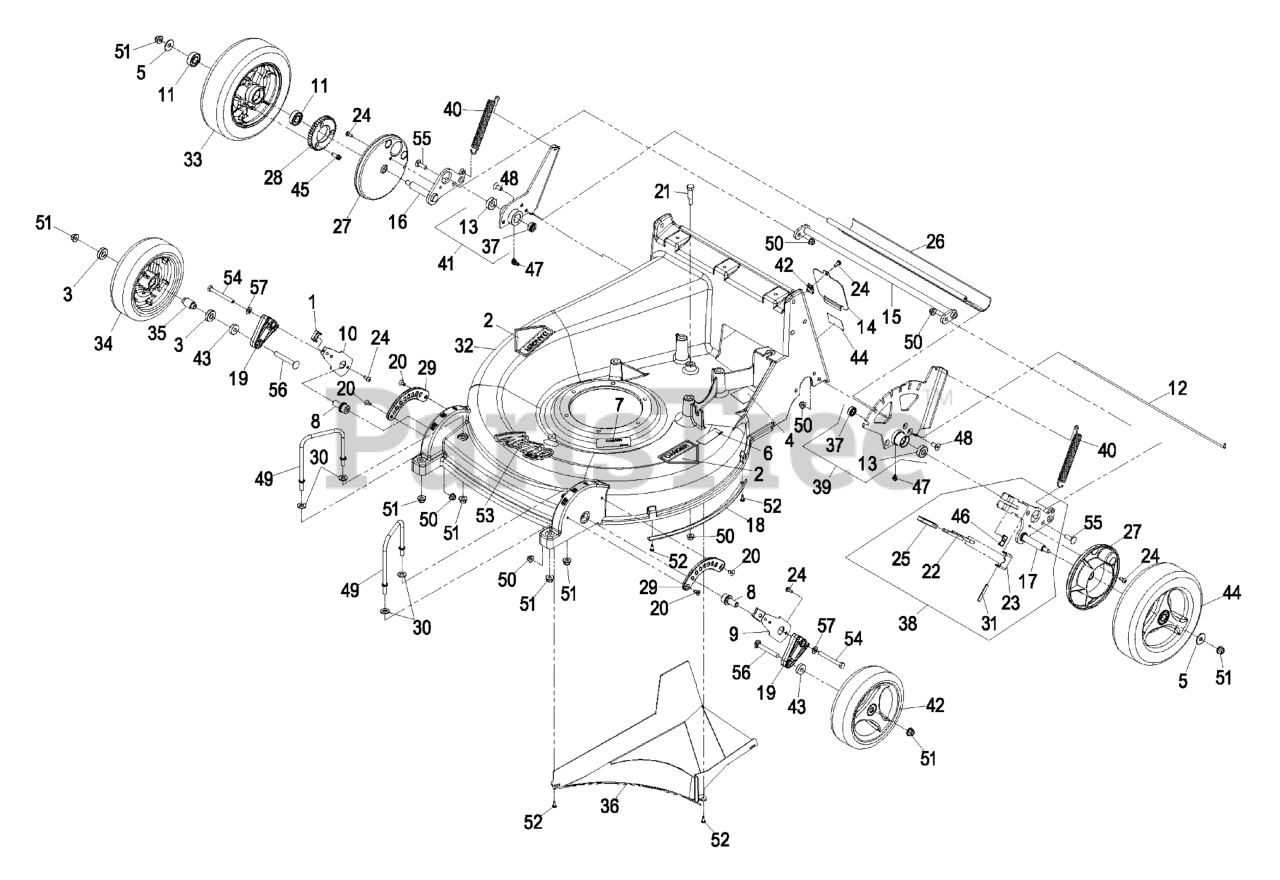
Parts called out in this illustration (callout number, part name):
1	KNOB-ARM
2	DECAL-DANGER
3	BEARING-WHEEL
4	Decal, Grease
6	DECAL-BLADE
7	DECAL-COVER, MISSING
8	BUSHING-PIVOT, WHEEL
9	LH FRONT SPRING ARM ASM
11	BEARING-BALL
13	BEARING-AXLE, REAR
16	Wld, Axle Arm Rh
18	GUARD-EDGE
21	SCREW-SHOULDER, HH
22	Lever, Lift
23	BRACKET-PIVOT, LIFT
24	SCREW-TP
25	COVER-HANDLE
27	COVER-GEAR
28	GEAR-DRIVEN
29	QUADRANT-FRONT
30	WASHER-FLAT
31	PIN-ROLL
32	ASM,26 DECK W/DECALS
33	ASM,10" TIRE AND WHEEL
34	ASM,8" WHEEL AND TIRE
35	SPACER-WHEEL, FRONT
37	SEAL-AXLE
38	ASM,REAR ADJUSTER
39	ASM,REAR QUADRANT
40	SPRING-ASSIST, LIFT
41	ASM,BEARING SUPPORT RH
42	Nut, Retainer-Panel 1/4-20
44	LABEL-GREASE, HP
45	SCREW-HWHTF
46	SPRING-LATCH
47	FITTING-GREASE
48	SCREW TORX FH - 5/16-18 X
50	NUT-HF, NI
51	NUT-HF, NI
52	SCREW-FORMING, THREAD
53	DECAL,METRO 26
54	SCREW-HH
55	BOLT-CARR
56	SCREW-CARR
57	WASHER-PLAIN
